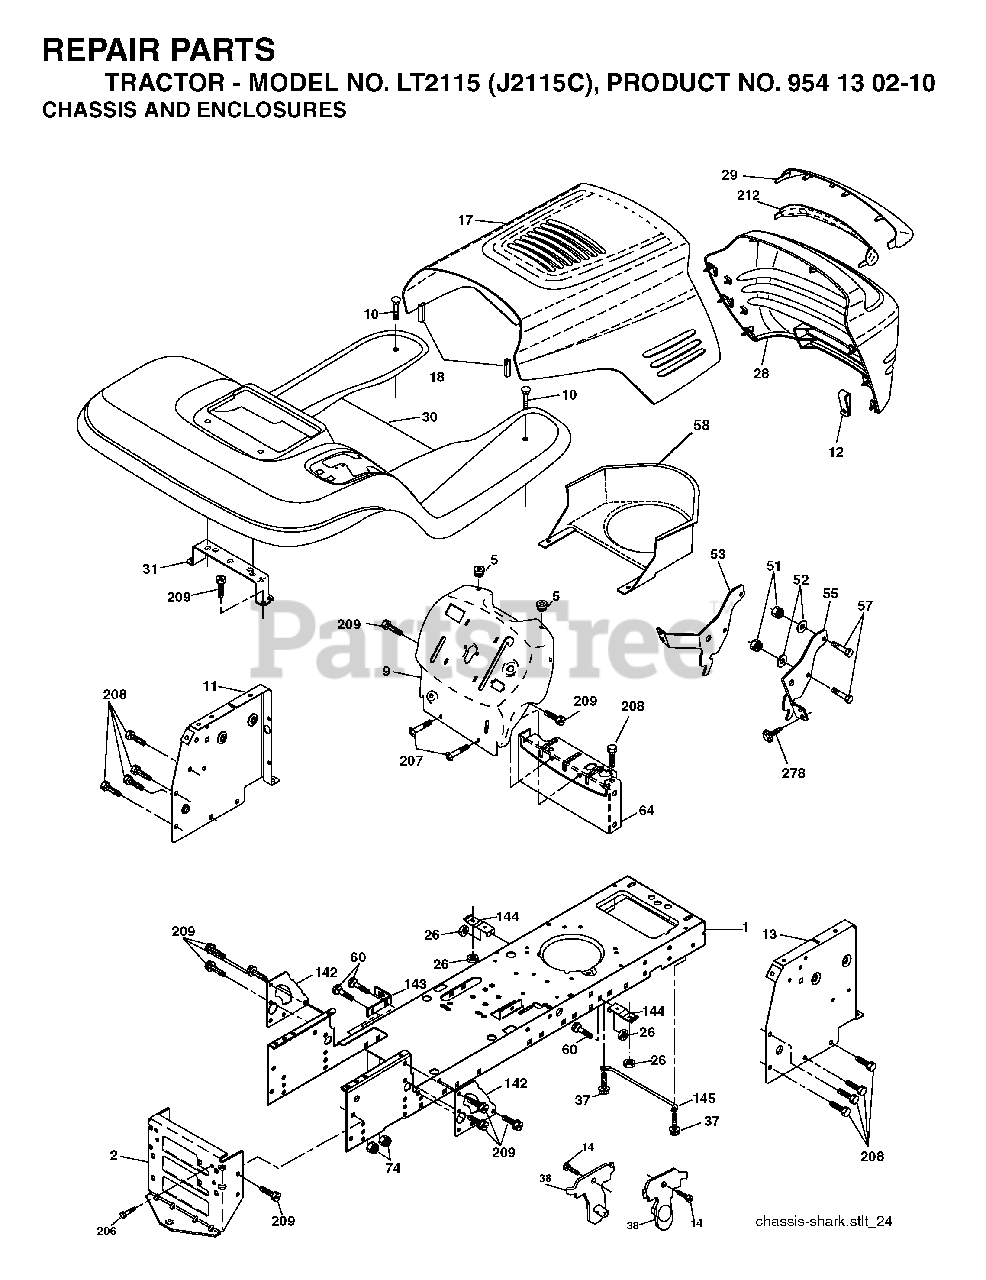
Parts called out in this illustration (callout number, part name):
1	CHASSIS STAMPING
2	DRAWBAR, 12GA
3	SCREW 3/8-16X3/4
5	BUMPER.RUBBER.HOOD
10	BOLT D
11	PANEL.DASH.LH.LTX
13	PANEL DASH RH
18	BUMPER.HOOD.LARGE.1.75"
26	NUT
38	BRACKET.ASM.PIVOT.MOWER.REAR
51	LOCKNUT
57	BOLT
64	DASH LOWER
74	LOCKNUT
142	PLATE REINFORCEMENT
143	BRACKET, SWAYBAR CHASSIS
144	BRKT, FOOT REST
145	ROD PIVOT CHASSIS/HOOD
206	SHOULDER BOLT 5/16-18TT
207	SCREW, 5/16-18 X 1/2
208	SCREW 3/8-16X1/2
209	SCREW, 3/8-16X3/4
278	SCREW
